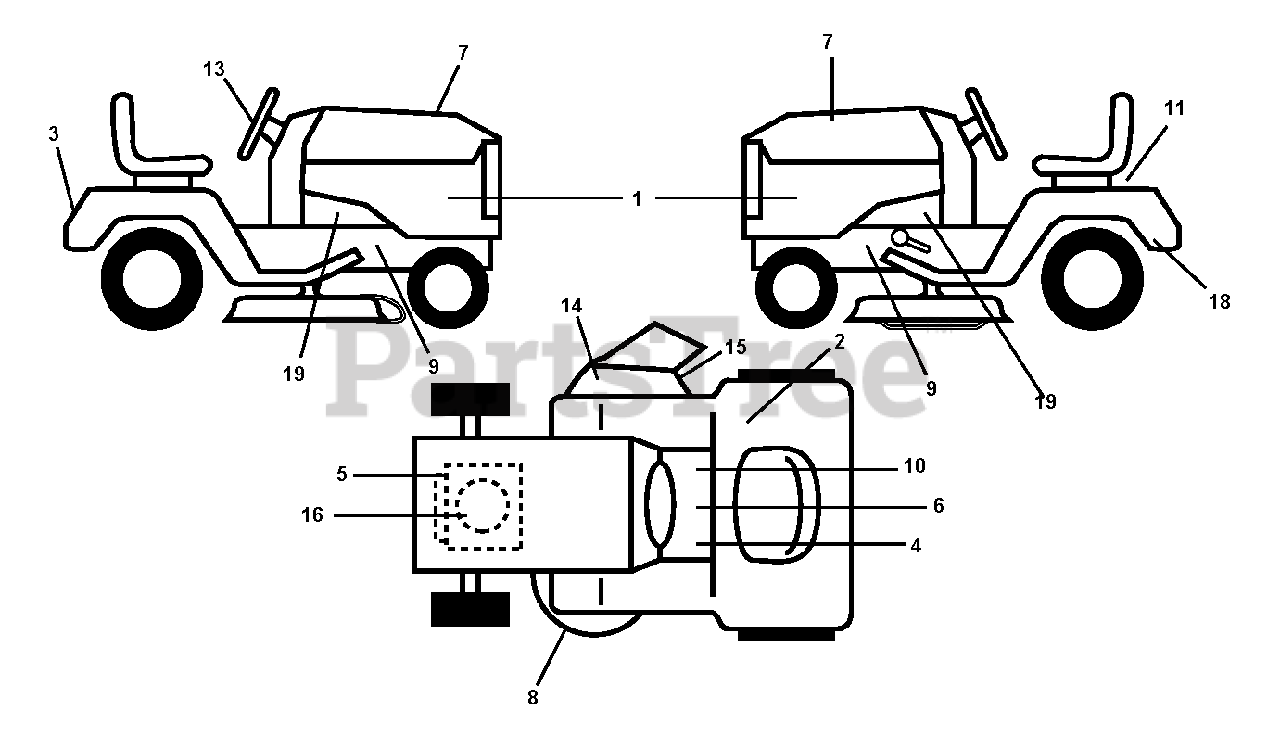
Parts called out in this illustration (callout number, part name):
2	Decal, 100 DB/CE
8	DECAL V BELT SCHEMATIC
10	DECAL PARK BRAKE
11	DECAL BTRY SYMBOLS
14	DECAL.INTERNATIONL.CUTFINGER
15	DECAL, DEFLECT WARNING
19	DECAL.CHAS.TURBO
